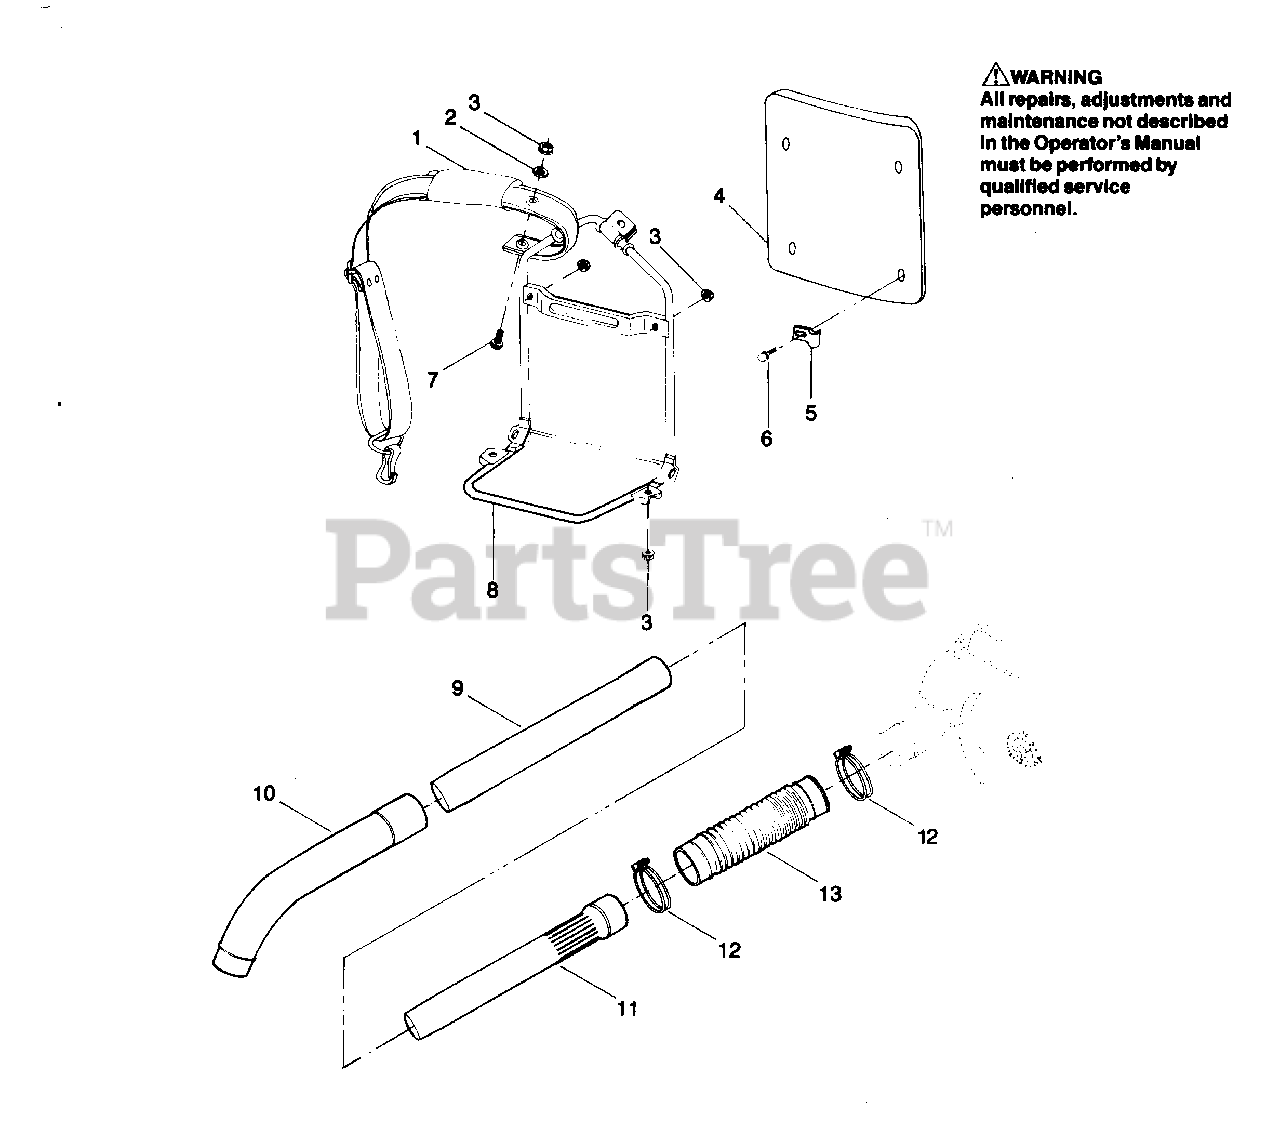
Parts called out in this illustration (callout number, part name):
1	Shoulder Band
2	Washer - Steel
3	Flange Nut (6mm)
4	Backpack Pad
5	Clamp - Back Pad
6	Bolt (5 x 12mm) - Hex - Sems
7	Screw (6 x 20mm)
8	Backpack Frame
9	Middle Tube
10	Bent Tube
11	Bast Tube
13	Flexible Tube
